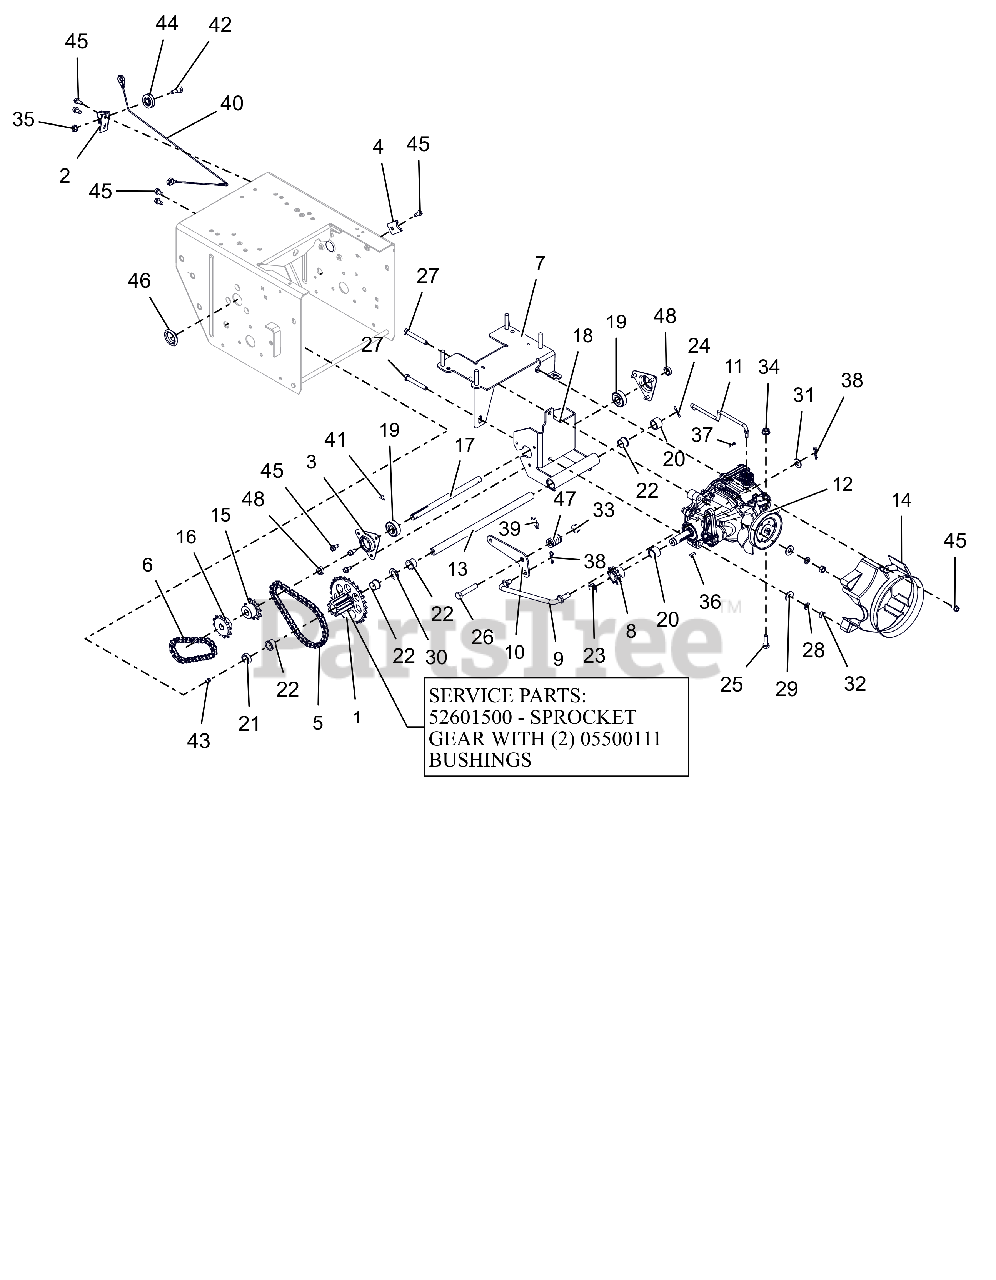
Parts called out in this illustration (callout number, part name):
1	PINION & SPROCKET
1	PINION & SPROCKET W/BUSHINGS
2	BRACKET, CABLE PULLEY
3	FLANGE, BEARING
4	TAB, ANTI ROTATION
5	ROLLER CHAIN #41 - 34 PITCHES
6	CHAIN-ROLLER #41X26 PITCHES
7	BRACKET, HYDROSTATIC TRANS XLG
8	SPROCKET, PINION 9T W/KEY
9	ROD, HYDRO TRANS SHIFT
10	PIVOT, HYDRO TRANS SHIFT
11	ROD, HYDRO BYPASS
12	TRANSMISSION, HYDROSTATIC
13	SHAFT, PINION - HARDENED
14	SHROUD, HYDROGEAR RT-310
15	SPROCKET, 11 TOOTH
16	SPROCKET, 12 TOOTH
17	SHAFT, REDUCTION HEAT TREATED
18	SUPPORT, REDUCTION-BWT
19	BRG-BALL .500X1.38X.437
20	SPACER, .635X.880X.611
21	BSHG-SLV, .635X.880X.305
22	BSHG-FLG .625X.750X.500X.875
23	RG-RTNG-EXT .625X.042
24	@PIN-GRV .125X1.00 TP E ALLOY
25	@BLT-HEX .31-18X1.00 GR5 YWZC
26	@BLT-HEX .38-16X2.00 GR5 YWZC
27	@BLT-HEX .31-18X2.25 GR5 YWZC
28	WSHR-LK .312X.097 HVY YWZC
29	@WSHR-FL-STL.38X.875X.083 YWZC
30	WSHR-FL-STL .630X1.005X.062 YZ
31	@WSHR-FL-STL.406X.812X.065 YWZ
32	@NUT-HEX .31-18 YWZC
33	@NUT-LK-TOP-FLG .38-16 YWZC
34	@NUT-LK-TOP-FLG .31-18 YWZC
35	@NUT-LK-TOP-FLG .25-20 YWZC
36	KEY-SQ .187 X .50 X .187
37	PIN-HAIR INT .06X.18X.77
38	PIN-HAIR INT .08X.18X1.18 YWZC
39	PIN, SPRING CLIP
40	CABLE, TRACTION, HYDRO PRO
41	CLIP, SPRING
42	BOLT, SHLDR-.375X.375X.25-20
43	ZERK,FITTING .25X.125 DRIVE IN
44	PULLEY, CABLE
45	SCR-TAP .25-20X.50 HWH TR YWZ
46	PLUG, HOLE - 1.125"
47	SG-COMP .187X.56X1.62
48	SPCR, SLV
